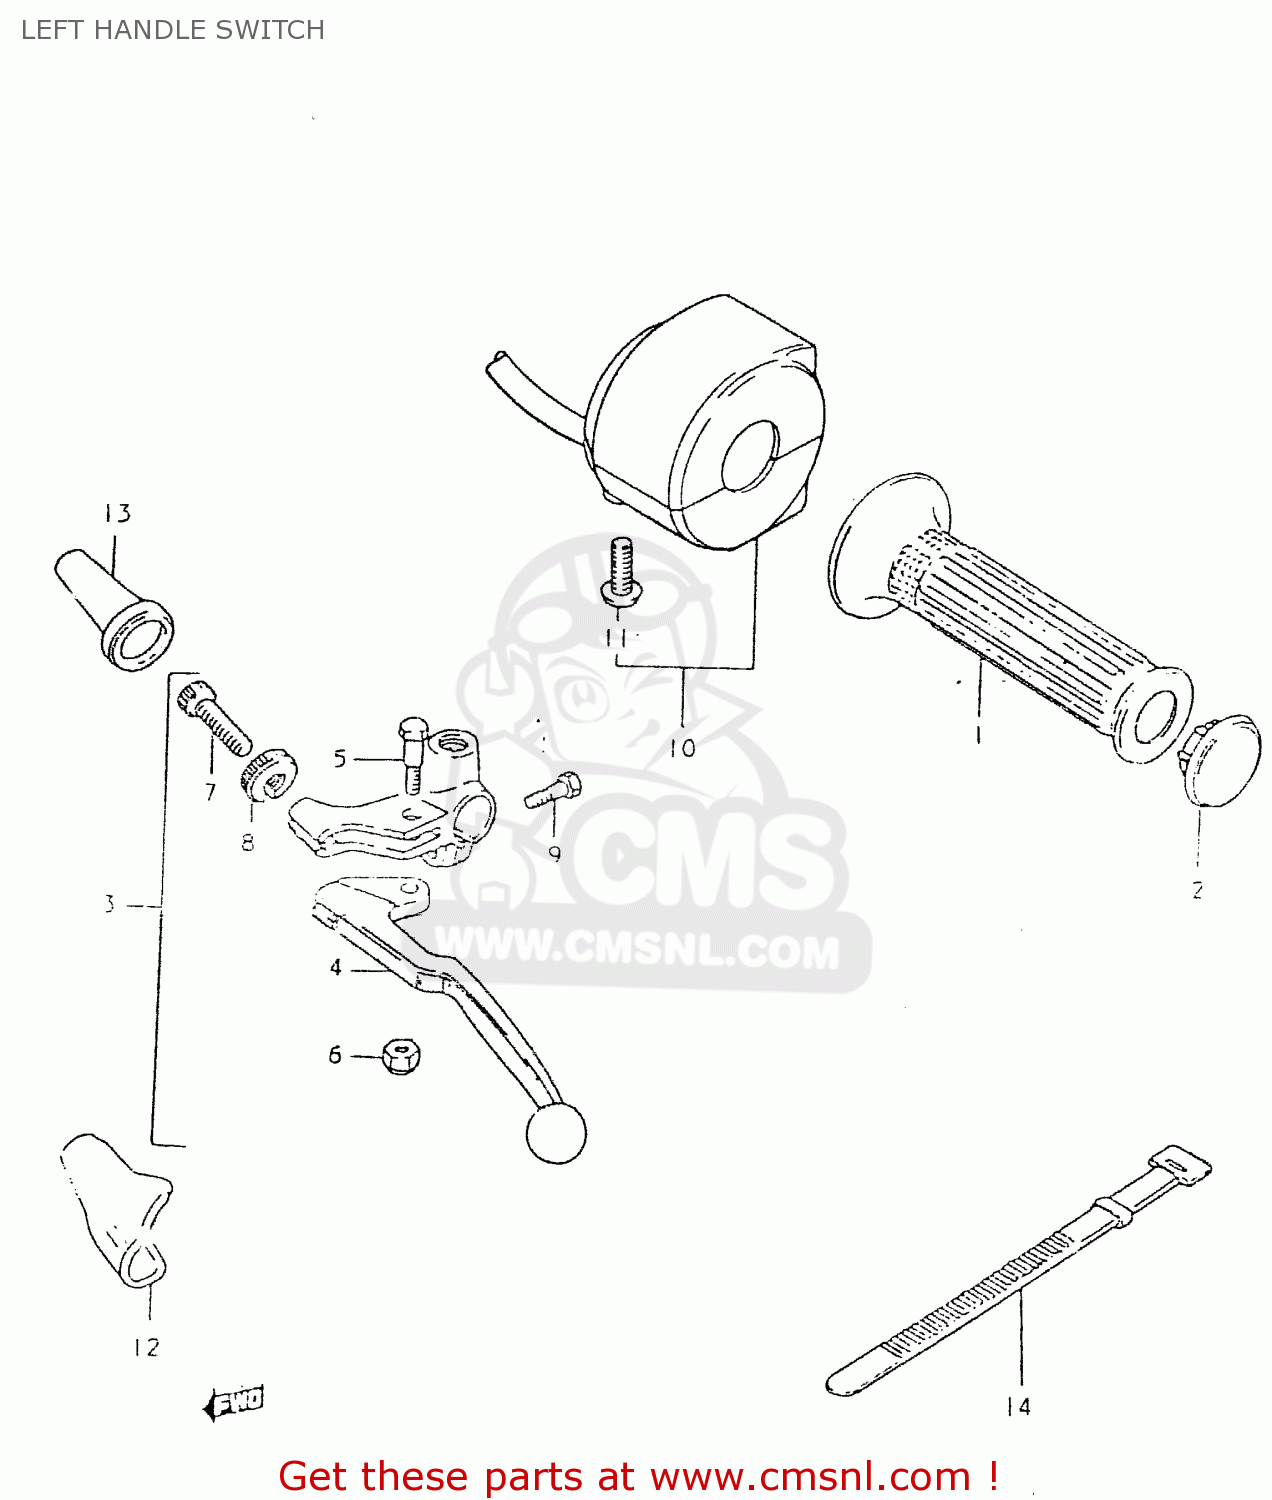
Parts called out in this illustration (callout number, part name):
1	GRIP,LEFT
2	CAP,GRIP END
3	LEVER ASSY, CLUTCH
4	LEVER,CLUTCH
5	BOLT,LEVER
6	NUT 6MM
7	ADJUSTER,CABLE
8	NUT,CABLE ADJUSTER
9	BOLT
10	SWITCH ASSY, HANDLE LH
11	SCREW
12	COVER,CLUTCH LEVER
13	BOOT,CLUTCH CABLE
14	CLAMP(L:120)
